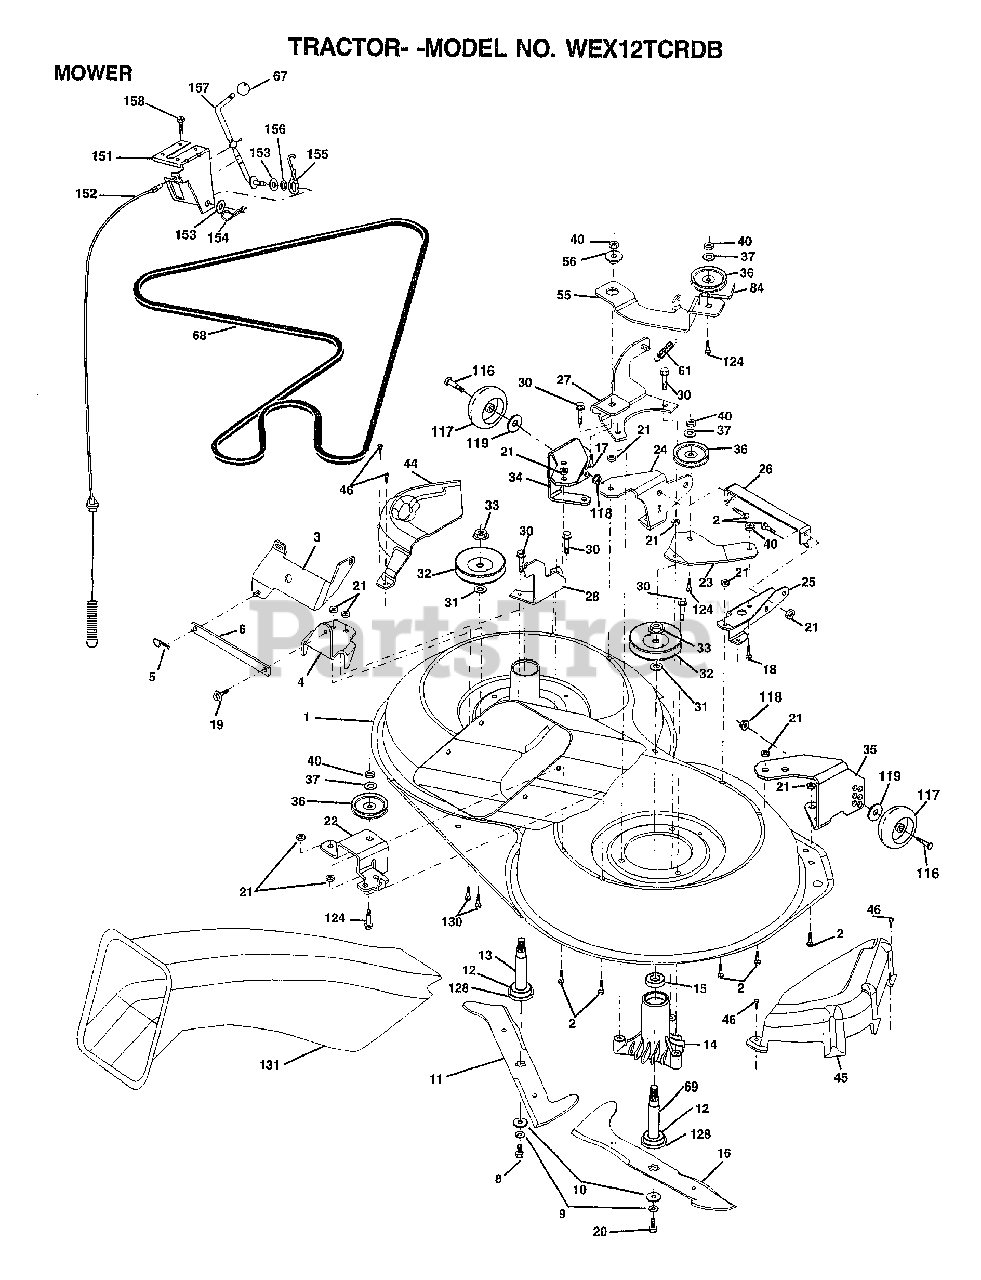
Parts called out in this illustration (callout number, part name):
1	HOUSING.ASM.MOWER
2	BOLT
3	BRKT.ASM.S-BAR.CHASSIS
4	BRKT.BAR.SWAY.DECK
6	BAR.SWAY.92.CRD
8	BLADE BOLT
10	WASHER.HARD.BLADE
11	BLADE
12	BEARING.BALL
14	HSG ASM MANDREL
15	BEARING
16	BLADE
17	BOLT.3/8-14X1.25
18	BOLT D
19	BOLT SHD 5/16-18
20	BOLT.3/8-24X1.25
22	BRKT.IDLER.SPRT.CRD
23	"BRKT.IDLER.SPRT.RF.92,CRD"
24	BRKT.SUSP.LF.92.CRD
25	BRKT.SUSP.RF.92.CRD
26	BRACE.SUPT.SUSP.FRT.CRD
27	BRKT.ASM.SUSP.RR.92.CRD
28	BRKT.ASM.SUSP.LR.92.CRD
30	"SCREW-THD ROLL,WA"
31	WASHER
32	PULLEY.MAND.36/46
34	BRKT.GUAGE.WHL.LF.92.CRD
35	BRKT.GUAGE.WHL.RF.92.CRD
36	PULLEY.IDLER.4.25
37	WASHER
44	COVER.MANDREL.LH.92.CRD
45	COVER.MANDREL.RH.92.CRD
46	SCREW.1/4-20X5/8
55	ARM.IDLER.92.CRD
56	SPACER.RETAINER.MOWER
61	SPRING.TENSION.BELT
67	KNOB T(3/8 HOLE)
68	HEX-BELT.92.MWR.105AA
69	SHAFT.ASM.W/LWR.BRG.RH.THD
84	"KEEPER-BELT,IDLER"
116	BOLT.SHOULDER
117	WHEEL GAGE DONUT
118	LOCKNUT
119	WASHER
124	BOLT.3/8-16X1.50
128	WASHER.FELT.
131	CHUTE.BAGGER.CRD
151	BRKT CLUTCH CABLE
152	CABLE CLUTCH CRD SERVICE
153	WASHER FLAT
154	SPRING RETAINER
155	SPRING RETENTION LVR CLUTCH CAB
156	SPACER
157	ROD.CLUTCH.CABLE.3/8
158	SCREW LT
